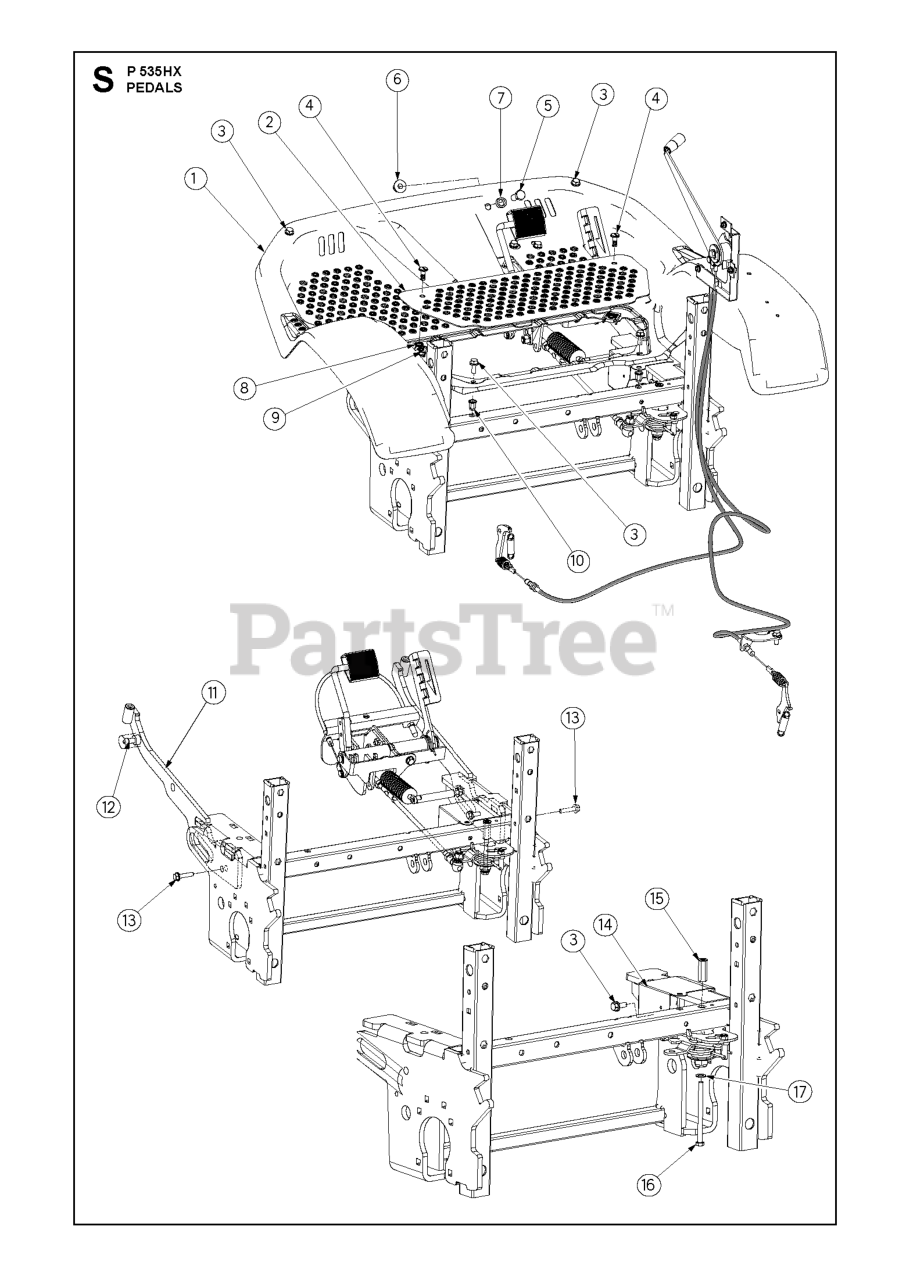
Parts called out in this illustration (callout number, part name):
5	Hex Head Capscrew, M12 X 1.75 X 30 DIN933ZP
13	SCREW EHHFM
16	Screw, Ehhm
